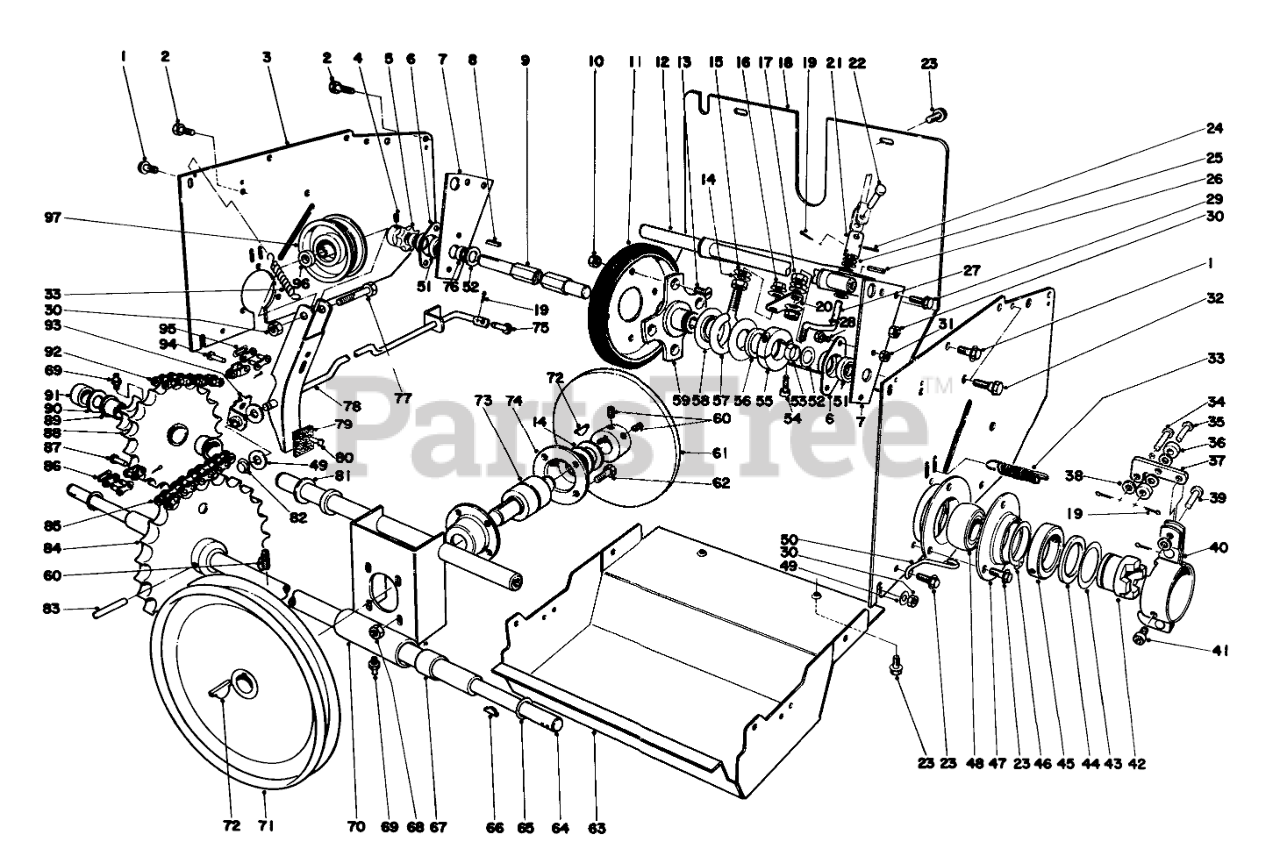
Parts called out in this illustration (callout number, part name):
1	SCREW-HHF
2	SCREW-HHFTF
3	Side Plate Drive
4	SCREW-HSH
5	SPROCKET
6	BEARING CUP
7	Mount Hex Shaft
9	FRICTION WHEEL SHAFT
10	Nut
11	Disc
12	Bracket Dead Shaft
13	5/16-18X5/8 FLT HD MS
14	WASHER-FLAT
15	WASHER-SPRING
16	NUT-LOCK, FLANGE
17	Nut
18	REAR COVER R
19	PIN-COTTER
20	SHIFT ROD PIVOT
21	U JOINT TUBE
22	CLEVIS PIN
23	SCREW-HWH
24	PIN-SPRING
25	Spacer
26	PIN-ROLL
27	CONNECTION ROD
28	SCREW-HH
29	SCREW-HWHTF
30	NUT-HEX
31	NUT-LOCK
32	SHOULDER SCREW
33	EXTENSION SPRING
34	PIN-CLEVIS
35	PIN-CLEVIS
36	CLUTCH ROLLER
37	CLUTCH CAM ARM
38	WASHER-FLAT
39	PIN-CLEVIS
40	CLUTCH MT BRKT ASM
41	Hex Socket Capscrew
42	Clutch Wheel
43	THRUST WASHER
44	THRUST BEARING
45	CLUTCH MOUNT COLLAR
46	RING-RETAINING, EXTERNAL
47	BEARING FLANGE
48	BEARING
49	WASHER-FLAT
50	Clutch Retainer
51	BEARING
52	WASHER-FLAT
53	SPLIT SPACER
54	SCREW-HSH
55	Collar
56	WASHER-THRUST
57	SLIDER RING COLLAR
58	SLIDER RING
59	TRACTION DISC HUB
60	Set Screw
61	Friction Plate
62	SCREW-HH
63	LOWER SHIELD R
64	Axle Shaft
65	WASHER
66	1/4X1-1/16 HI-PRO KEY
67	BUSHING
68	NUT-KEPS
69	FITTING-GREASE
70	Bulkhead (Incl. Ref. #67)
71	Pulley
72	KEY-WOODRUFF
73	Friction Plate Shaft
74	HOUSING BEARING
75	PIN-CLEVIS
76	SPACER
77	SCREW-HH
78	Auger-Idler (Incl. Ref. #79-80)
79	BRAKE PAD
80	.185 DIA X .375 RT +
81	THRUST WASHER
82	PUSH NUT
83	PIN-GROOVE
84	Lower Sprocket
85	ROLLER CHAIN
86	LINK-CHAIN
87	LINK-OFFSET
88	Sprocket (Incl. Ref. #69 & 89)
89	3/4ID X 3/4LG BSHG
90	WASHER-THRUST
91	SPACER-IDLER
92	1/4 X 42 CHAIN W/LINK
93	Bracket-Clutch
94	1/4 OFFSET LINK
95	LINK-CONNECTING
96	Spacer
97	PULLEY-IDLER
